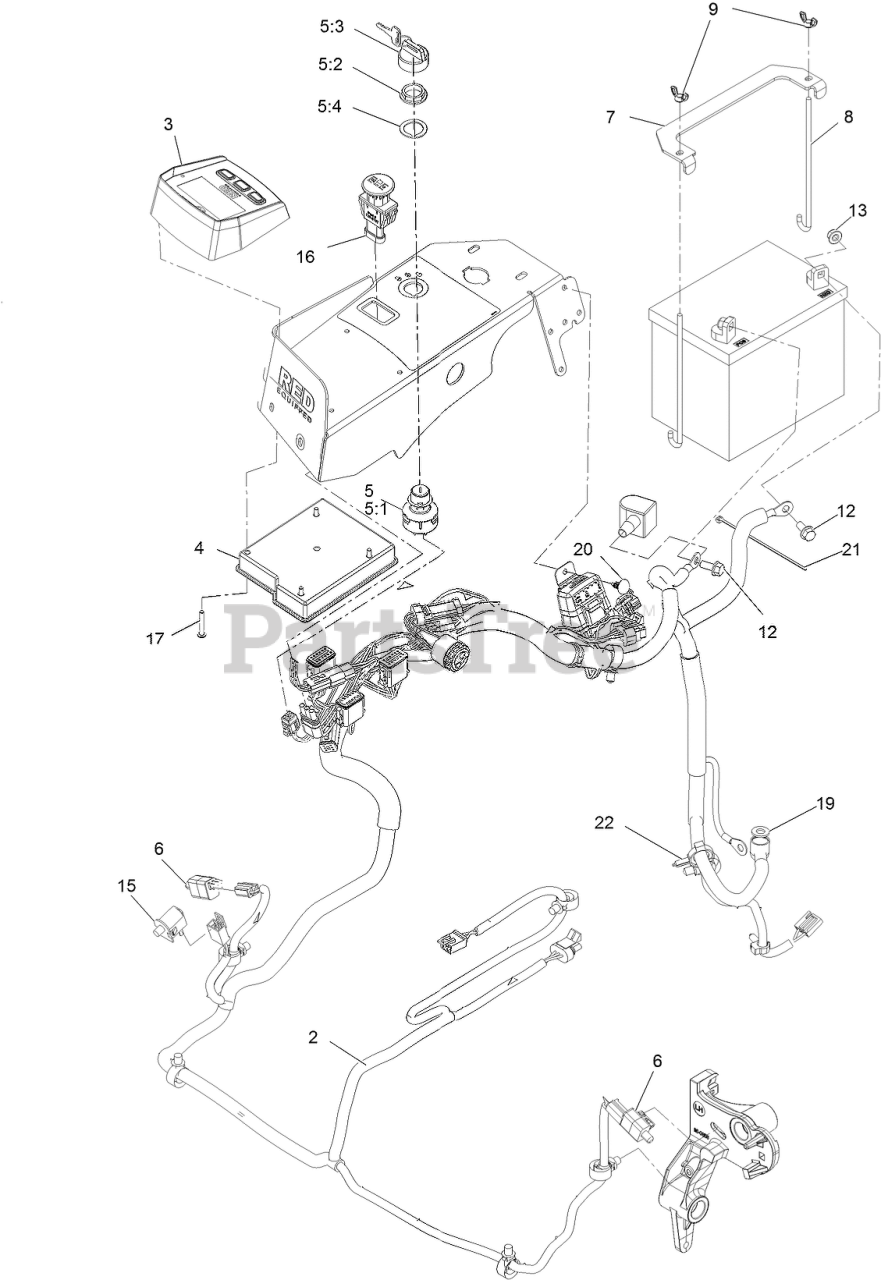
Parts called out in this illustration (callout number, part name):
2	HARNESS-WIRE
3	MODULE, LDU
4	Module-Mcu
5	IGNITION SWITCH ASM
5:1	Switch-Ignition
5:2	NUT-MOUNTING
5:3	IGNITION KEY SET
5:4	WASHER-BACKUP
7	STRAP-TIE DOWN, BATTERY
8	BOLT-HOLDDOWN
9	WINGNUT
12	SCREW-HHF
13	NUT-HF, NI
15	SWITCH-BAIL
16	SWITCH-PTO, SEALED
17	SCREW-PPH
19	WASHER-FLAT
20	PLUG-PLASTIC
21	TIE-CABLE
22	CLAMP-HOSE
